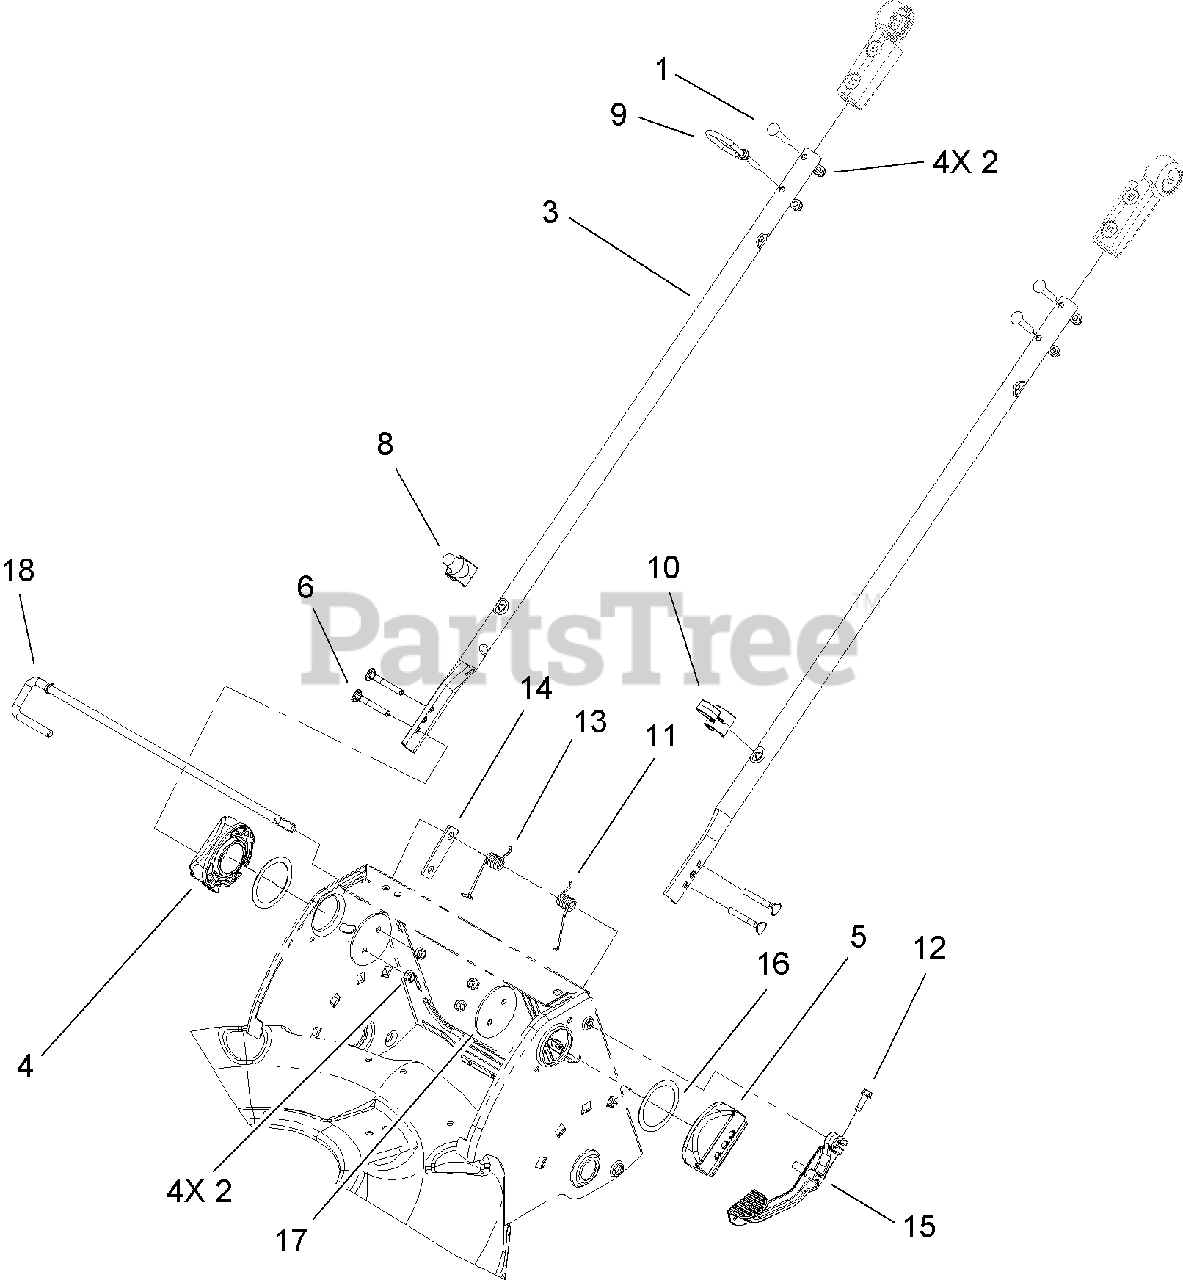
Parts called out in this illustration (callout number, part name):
1	SCREW-CARR
2	NUT-LOCK, NI
4	MOUNT-HANDLE, RH
5	MOUNT-HANDLE, LH
8	GUIDE-ROPE, LOWER
9	GUIDE-ROPE, UPPER
10	Guide-Cable
11	SPRING-TORSION, LH
12	SCREW-HWHTF
13	SPRING-TORSION, RH
14	PLATE-LOCK, HANDLE
15	LEVER-RELEASE
16	WASHER-NYLON
18	ROD-HANDLE RELEASE
